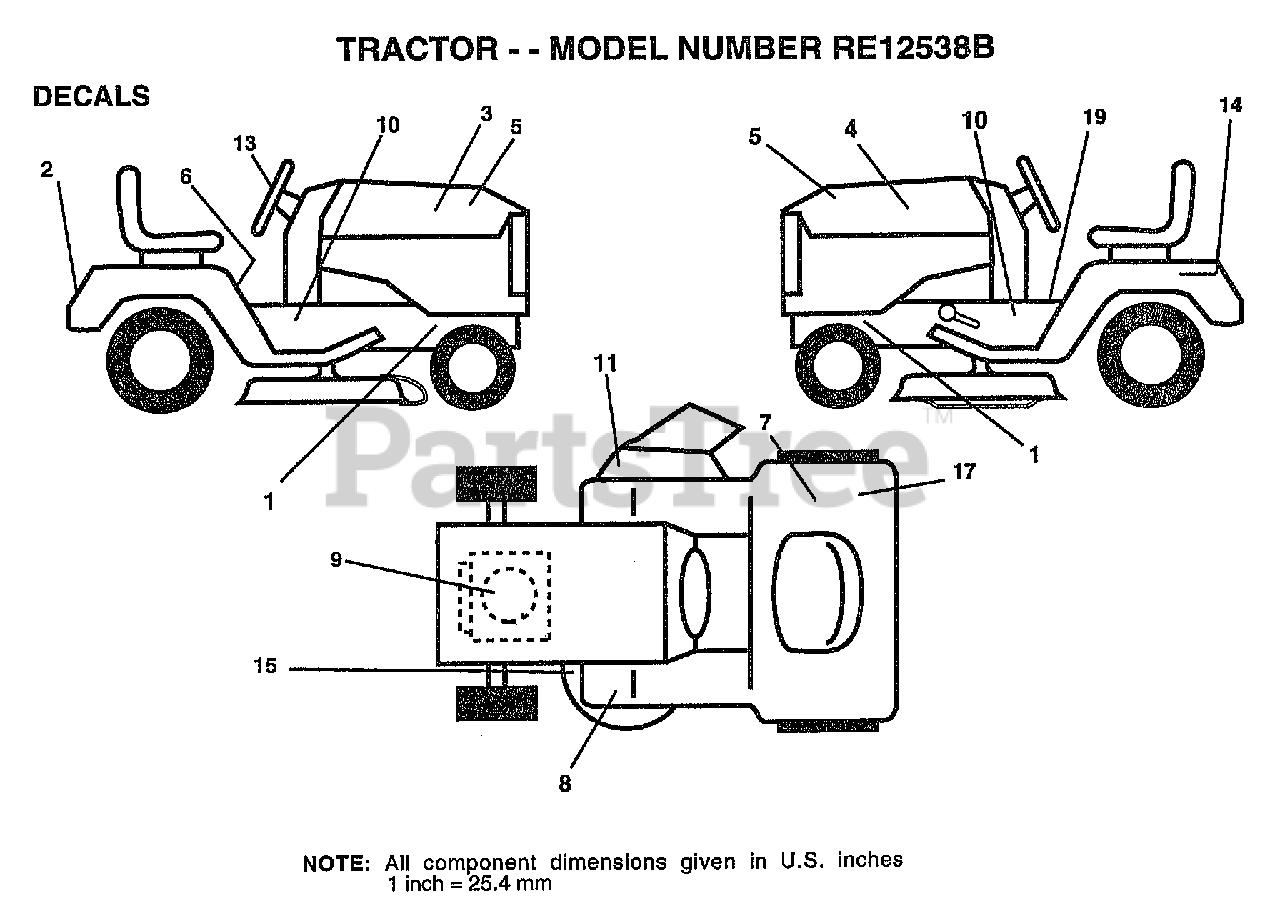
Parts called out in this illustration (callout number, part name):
1	"DECAL CHASSIS,HOT"
2	FENDER DECAL
3	DECAL HOOD RH
4	DECAL HOOD LH
5	DECAL.INS.HD.12.5
6	DECAL.READ.O.MANU
7	DECAL.EURO.ST.CE.
8	DECAL-BRAKE/CLUTC
9	DECAL, ENGINE
10	DECAL CHASSIS SPEED DECK
11	DECAL.DANGER.CUTF
13	"DECAL,STR WHL"
14	DECAL.BATRY.3-3908
15	DECAL
19	DECAL BRAK PARK
